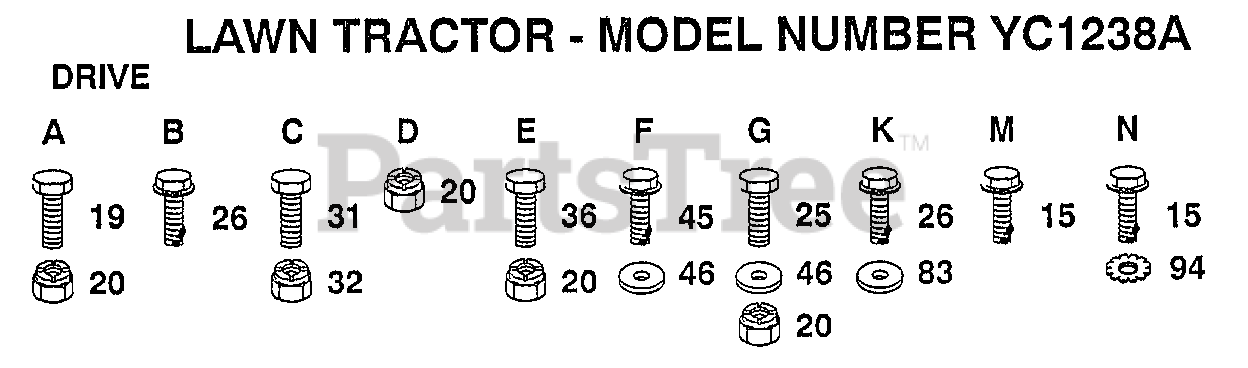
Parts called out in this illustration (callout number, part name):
15	SCREW
19	BOLT
25	BOLT
26	SCREW
31	BOLT
45	SCREW
46	WASHER
83	WASHER
94	LOCKWASHER
